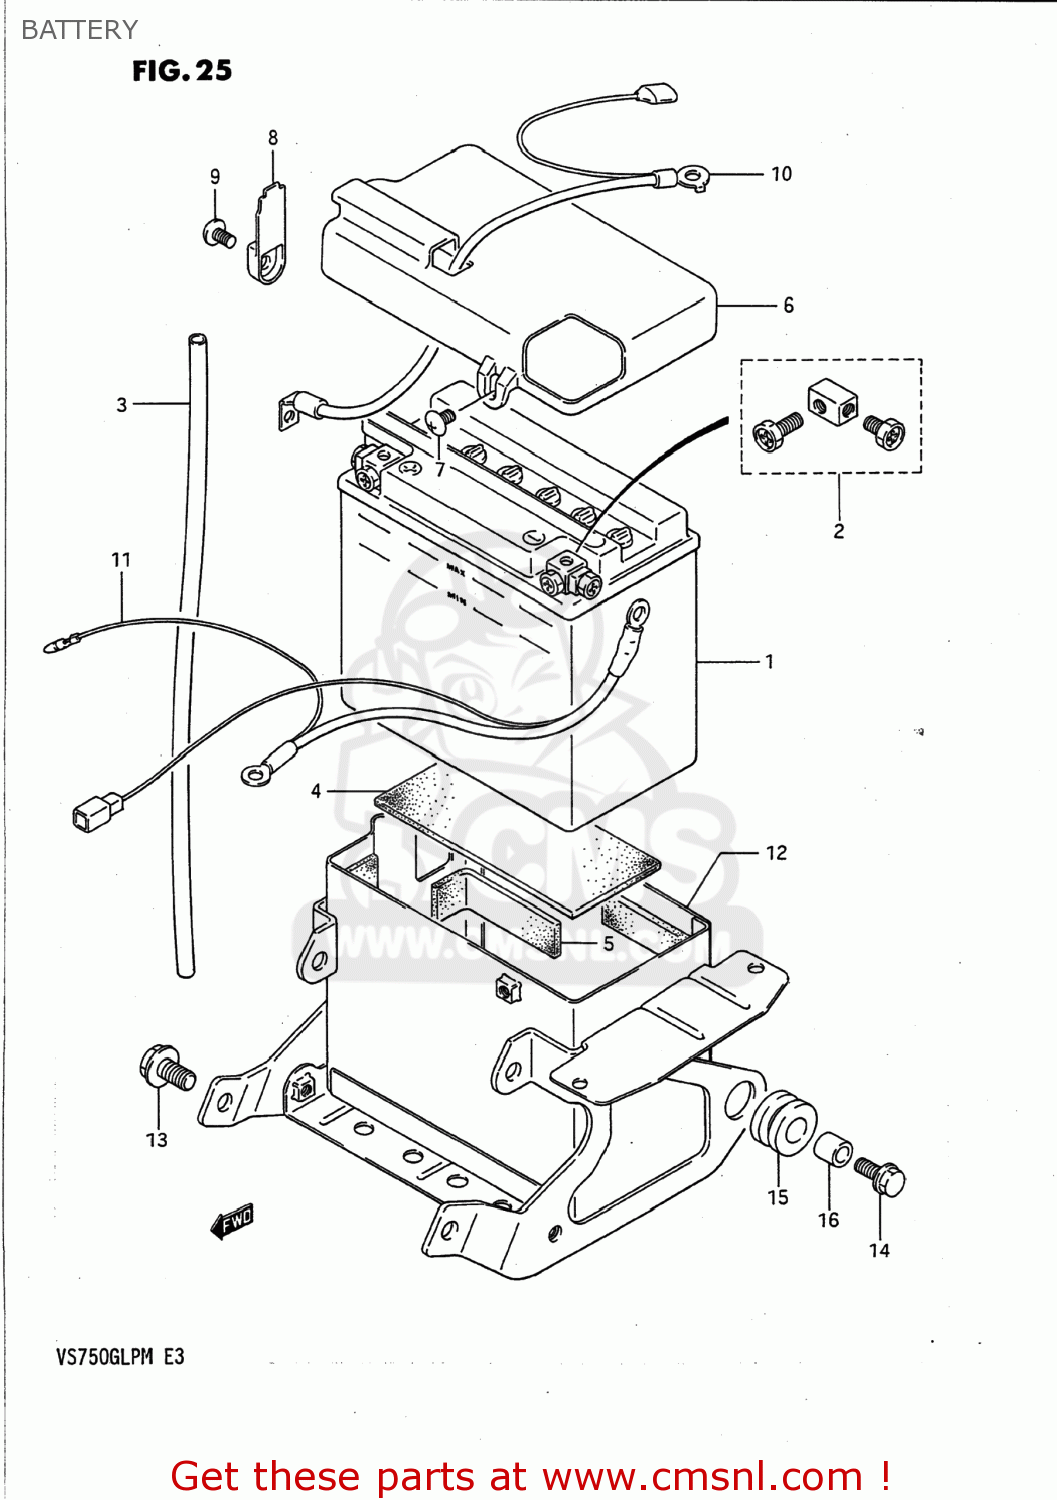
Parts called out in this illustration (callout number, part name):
1	BATTERY ASSEMBLY (12V)
2	BOLT SET,BATTERY TERMINAL
3	HOSE,BATTERY EXHAUST
4	PROTECTOR(170X95X3.0)
5	PROTECTOR(20X90)X2
6	COVER,BATTERY UPR
7	SCREW
8	COVER,BATTERY TERMINAL
9	SCREW
10	WIRE,BATTERY PLUS LEAD
11	WIRE,BATTERY MINUS LEAD
12	HOLDER,BATTERY
13	BOLT
14	BOLT
15	CUSHION
16	SPACER (8.8X12X11)
